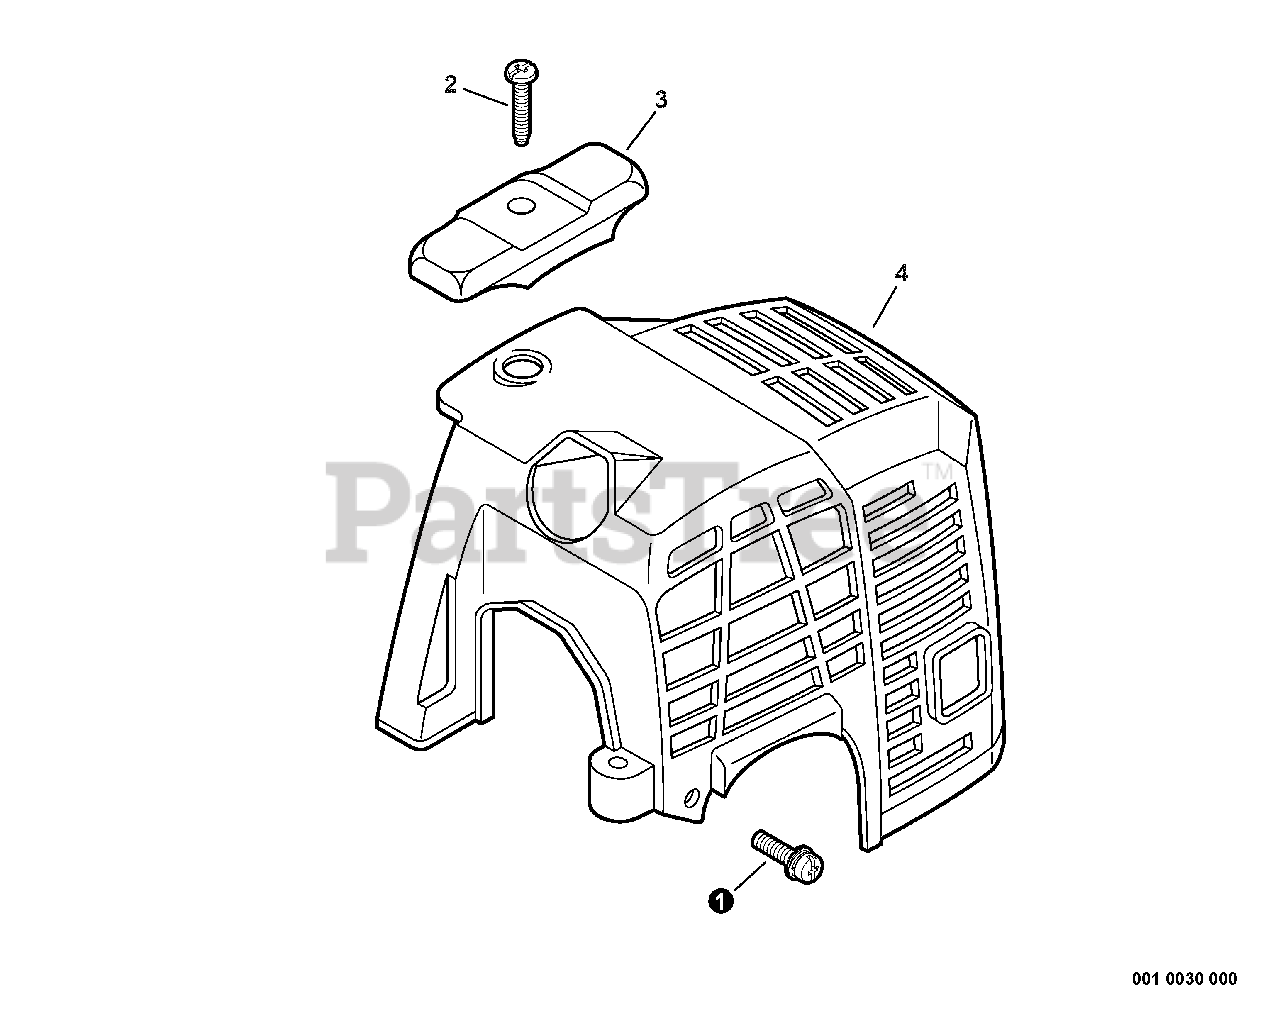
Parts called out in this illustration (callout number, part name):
1	SCREW - 4X16
2	SCREW - 5X20
3	GUARD - TOP
4	COVER, ENGINE
